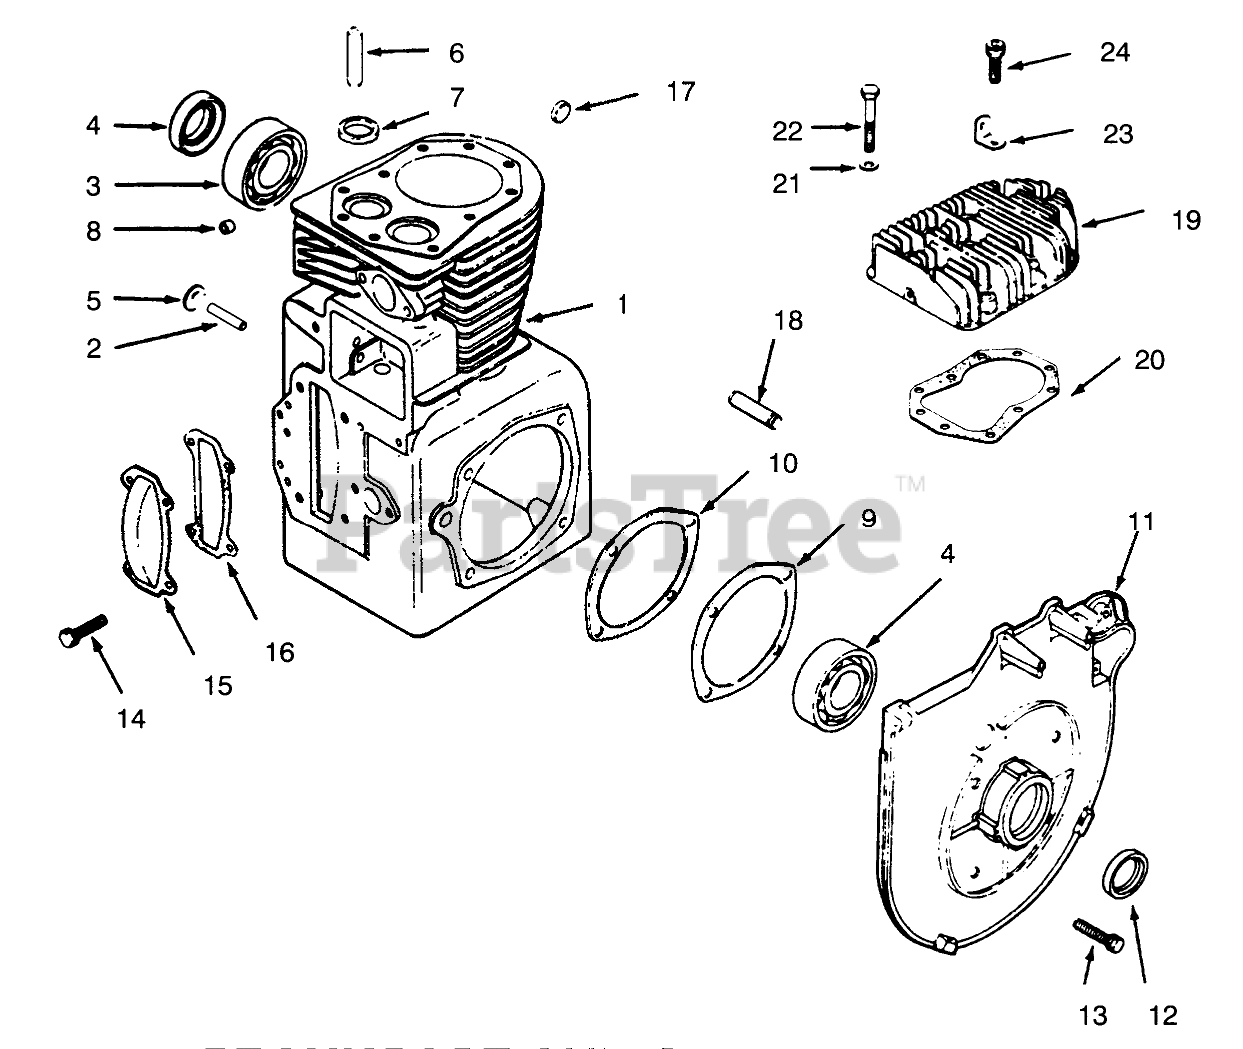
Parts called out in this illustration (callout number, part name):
1	Short Block (Includes Crankshaft)
2	Shaft-Governor Gear
3	Ball Bearing
6	Guide-Valve
7	Insert-Exhaust Valve
8	Bearing
9	Gasket
10	Gasket
11	Bearing Plate
13	Screw
14	Screw
15	Cover
16	Gasket
18	Shaft-Balance Gear
19	Cylinder Head
20	Gasket
21	Washer
22	Screw
23	Lifting Strap
24	Screw
